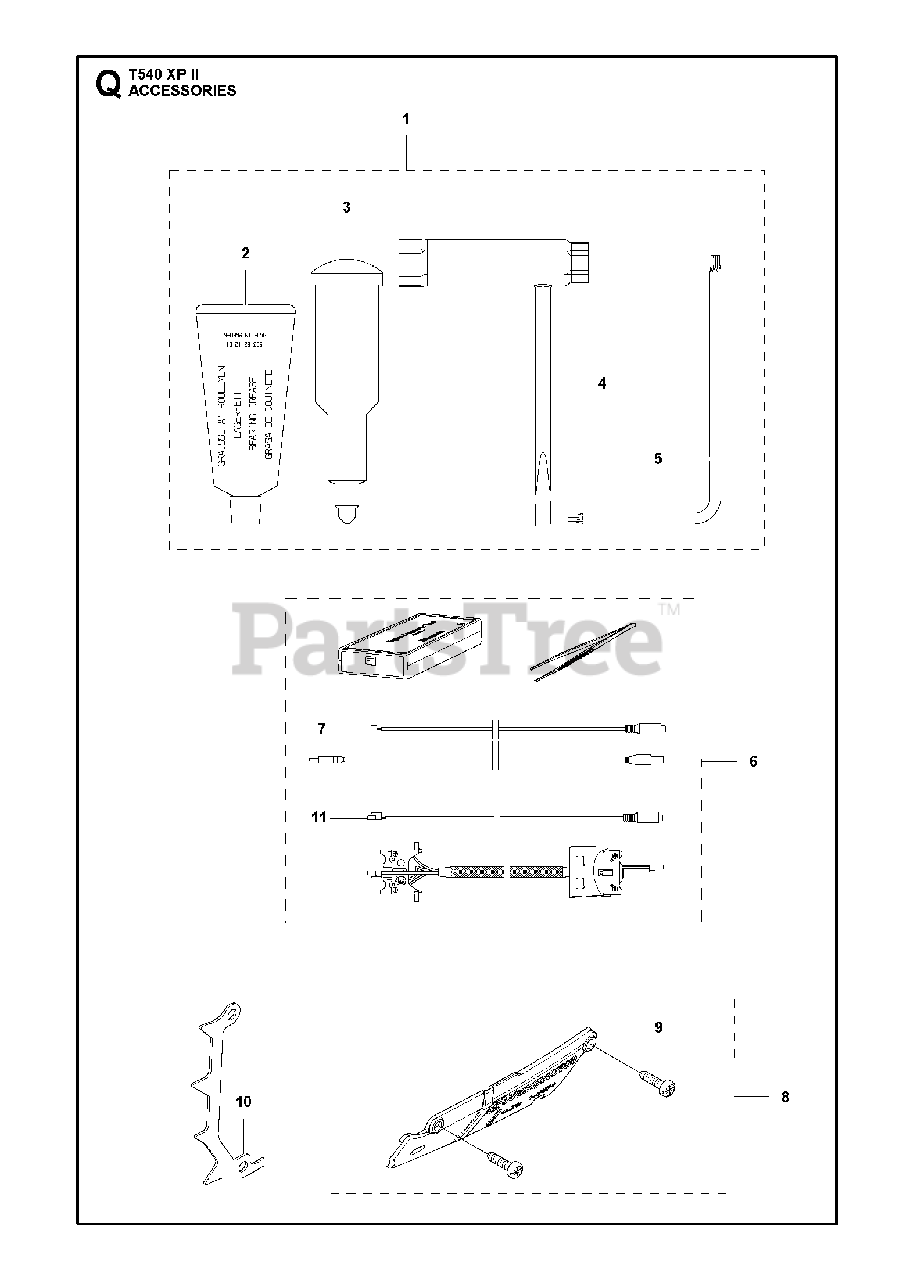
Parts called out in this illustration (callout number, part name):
2	GREASE
3	Grease Gun
4	COMBINATION WRENCH
6	DIAGNOSTIC TOOL KIT
7	CABLE ASSY
8	WINTER KIT
9	SCREW
11	CABLE ASSY
